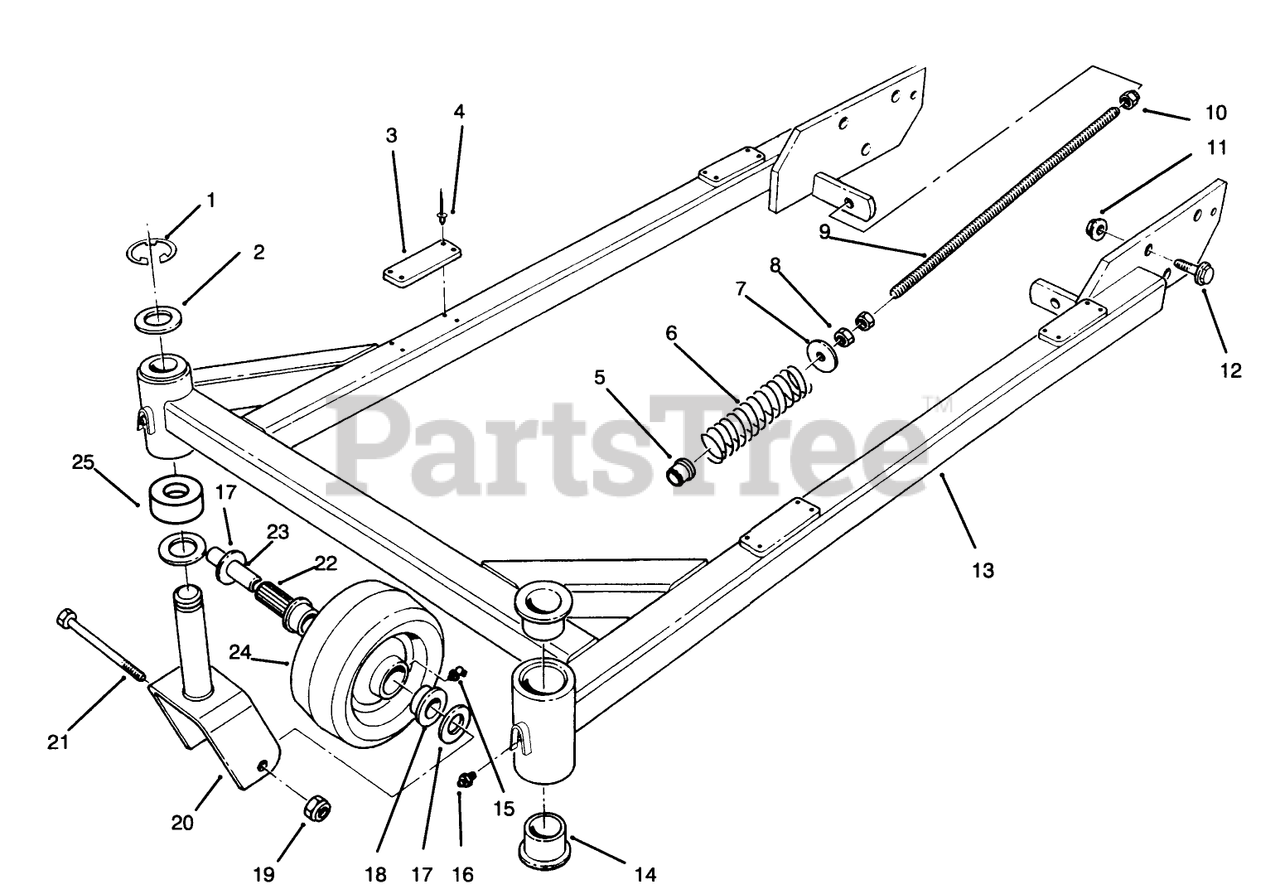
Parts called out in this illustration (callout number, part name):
1	RING-RETAINING
2	WASHER-THRUST
3	PAD-RUBBER
4	RIVET
5	BUSHING-FLANGE
6	SPRING
7	WASHER
8	NUT-JAM
9	SHAFT-ADJUSTING
10	NUT-LOCK, NI
11	NUT-HF
12	SCREW-HHF
13	Carrier Frame Assembly (Incl. Ref. #3,4,14 & 16)
14	BUSHING
15	FITTING-LUBE, 45 DEG
16	FITTING-GREASE
17	SPACER-WHEEL
18	BEARING-OUTSIDE
19	NUT-HEX
20	Fork-Castor
21	SCREW-HH
22	BEARING-ROLLER
23	SPANNER
24	Wheel Assembly-Castor (Incl. Ref. #15,18, & 22)
25	SPACER-CASTOR
